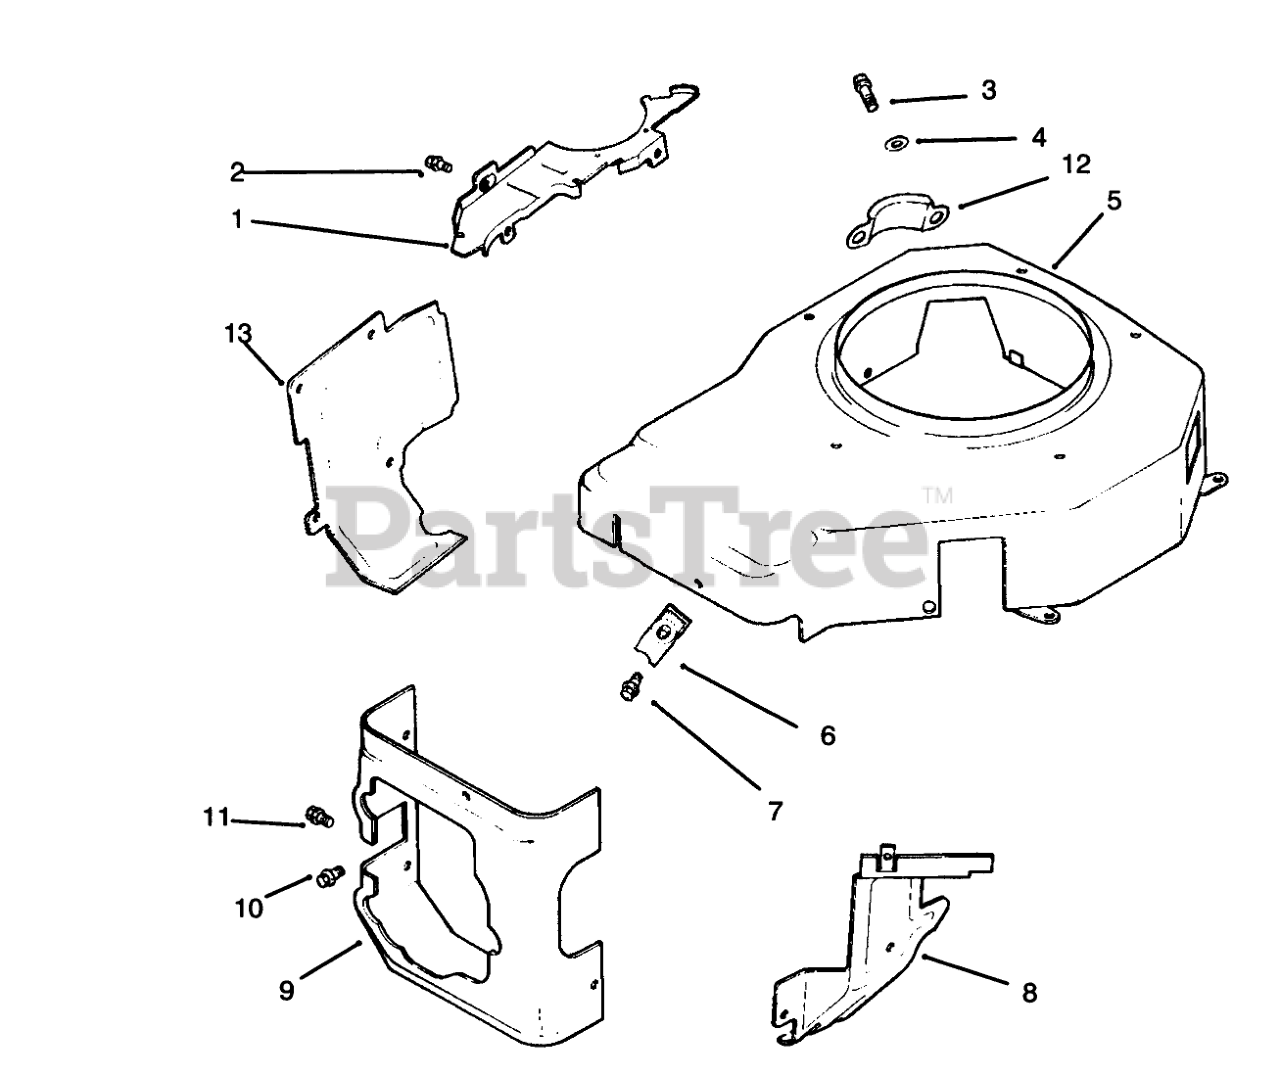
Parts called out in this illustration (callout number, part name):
1	Plate Blower
2	Screw
4	Washer
5	Housing-Blower
6	Clip
7	Screw
8	Bade-Carburetor
9	Baffle-Cylinder Head
10	Screw
11	Screw
12	Cover-Pinion
13	Babe-Cylinder Barrel
